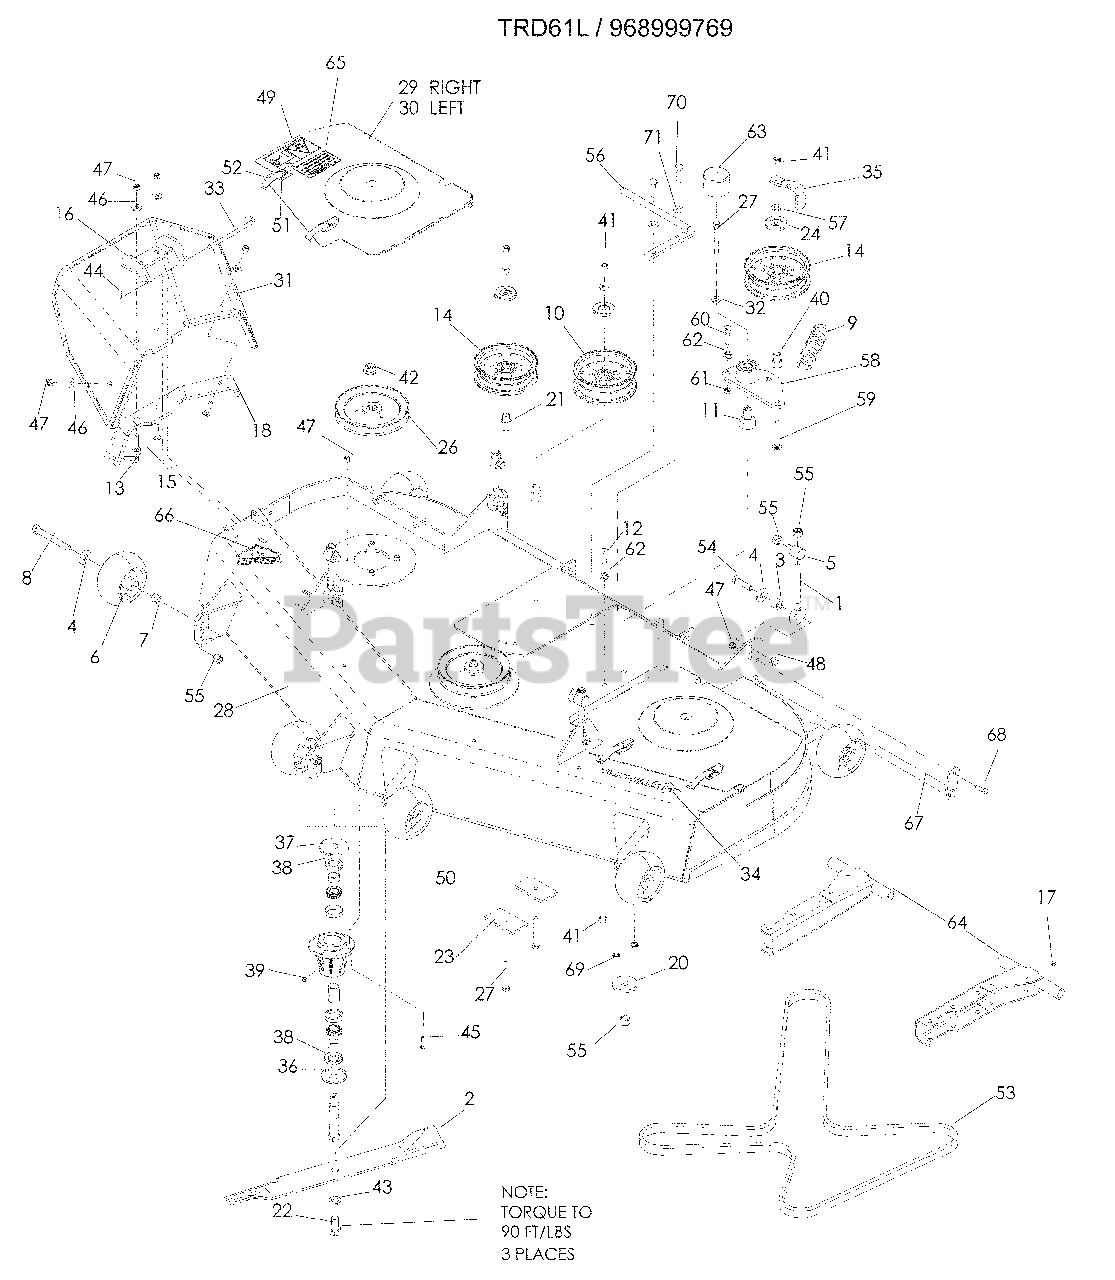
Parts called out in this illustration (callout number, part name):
2	BLADE, 21"
6	WHEEL, GAUGE
8	HCS ½-13 x 4
10	PULLEY, IDLER
11	PIVOT, BEARING
12	HCS 3/8-16 x 1¼
13	RHSNB 5/16-18 x 1¼
14	PULLEY, IDLER
15	RHSNB 5/16-18 x 1½
16	BRACKET, RUBBER CHUTE
17	ZERK, STRAIGHT, ¼-28
18	REINFORCEMENT, BRCKET
19	WASHER 9/16
20	SUPPORT WASHER
21	BUSHING, IDLER
22	HCS 5/8-18 x 1¼
23	PAD
24	SHIELD, DUST
25	HCS ½-13 x 3¼
27	HCS 3/8-16 x 3
28	DECK w/ DECALS
29	BELT SHIELD, RIGHT
30	BELT SHIELD, LEFT
31	DISCHARGE CHUTE
32	WASHER½ BELLEVILLE
33	PIN, CHUTE PIVOT
34	DECAL, TUNNEL RAM
35	GUIDE, BELT
36	DUST CAP, BOTTOM
37	DUST CAP, TOP
38	SHAFT SEAL
39	GREASE POPPET
40	BUSHING, IDLER
41	NUT 3/8-16 NYLOC
42	NUT ¾-16 FLANGE
43	LOCKWASHER 5/8
44	PIN COTTER, 1/8 x ¾
45	HCS 5/16-18 x 1¼
46	WASHER 5/16
47	NUT 5/16-18 NYLOC
48	NUT 7/16-14 CNTRLCK,GR A
49	DECAL, SEVERING
50	SPINDLE ASSEMBLY
52	DRAW LATCH
54	HCS 7/16-14 x 1¾
55	NUT ½-13 NYLOC
56	BELT GUIDE
57	WASHER 3/8 THICK
58	ARM w/ BEARINGS, IDLER
59	RHSNB 3/8-16 x 2¾
60	HCS 3/8-16 x 1½ GR8
61	NUT 3/8-16 JAM
62	NUT 3/8-16 WHIZLK
63	CAP, VINYL
65	DECAL, WARNING
66	DECAL, CPSC
68	HCS 5/16-18 x 1
69	NUT ¼-20, FLANGE
70	HCS ¼-20 x 1
71	WASHER ¼ SAE
